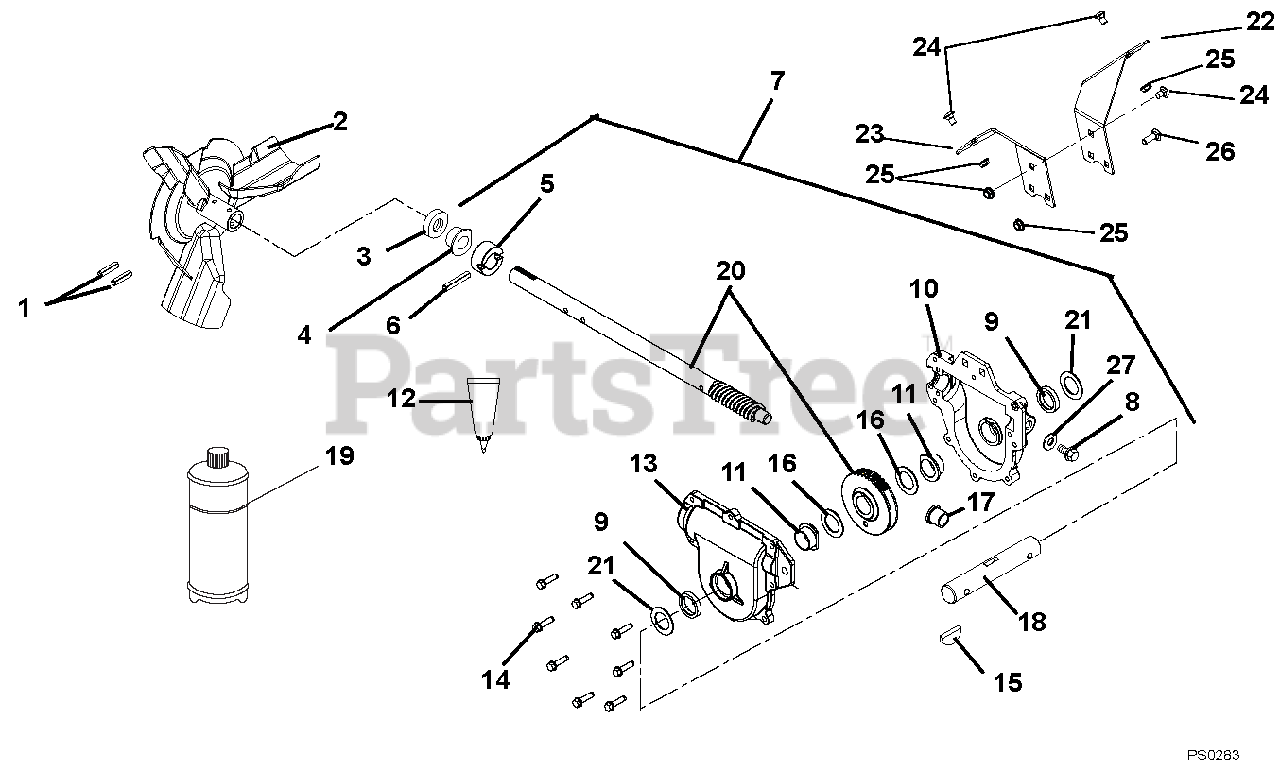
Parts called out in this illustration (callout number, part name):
1	PIN-ROLL .250X1.75
2	IMPELLER, 3 BLADE-14"
3	SEAL-OIL .875X1.375X.25 RBR OD
4	BSHG-FLG .876 X 1.500 X .750
5	THRUST COLLAR, .875" ID
6	PIN-GRV .250X1.50 TP E
7	GEAR CASE ASSEMBLY - COMMON
8	SCR-TAP .38-16X.75 ROLOK YZ WX
9	SEAL-OIL 1.000X1.375X.250
10	GEARCASE, ALUMINUM, LH
11	BSHG-FLG 1.003X1.5X.625
12	LOCTITE 518 GASKET--6ML TUBE
13	GEARCASE, ALUMINUM, RH
14	@SCR-TAP .25-20X1.00 HWH TR YZ
15	KEY-WDRF .25X.875 HRD #A
16	WSHR-HRD-THRS 1.007X1.542X.062
17	BSHG-FLG .629 X 1.000 X .750
18	RAKE SHAFT, SHORT-COMMON
19	ARIENS 16 OZ.BOTTLE OF L2 LUBE
20	WORM SHAFT & GEAR
21	WSHR-FL-STL 1.010X1.505X.062YZ
22	BRACKET, GEAR CASE SUPPORT-LH
23	BRACKET, GEAR CASE SUPPORT-RH
24	@BLT-RHDSSQNK .31-18X.62 G5YZ
25	@NUT-LK-TOP-FLG .31-18 YWZC
26	@BLT-RDHDSQNK .31-18X1.00 G5YZ
27	WSHR-FIBER .437X.656X.032
